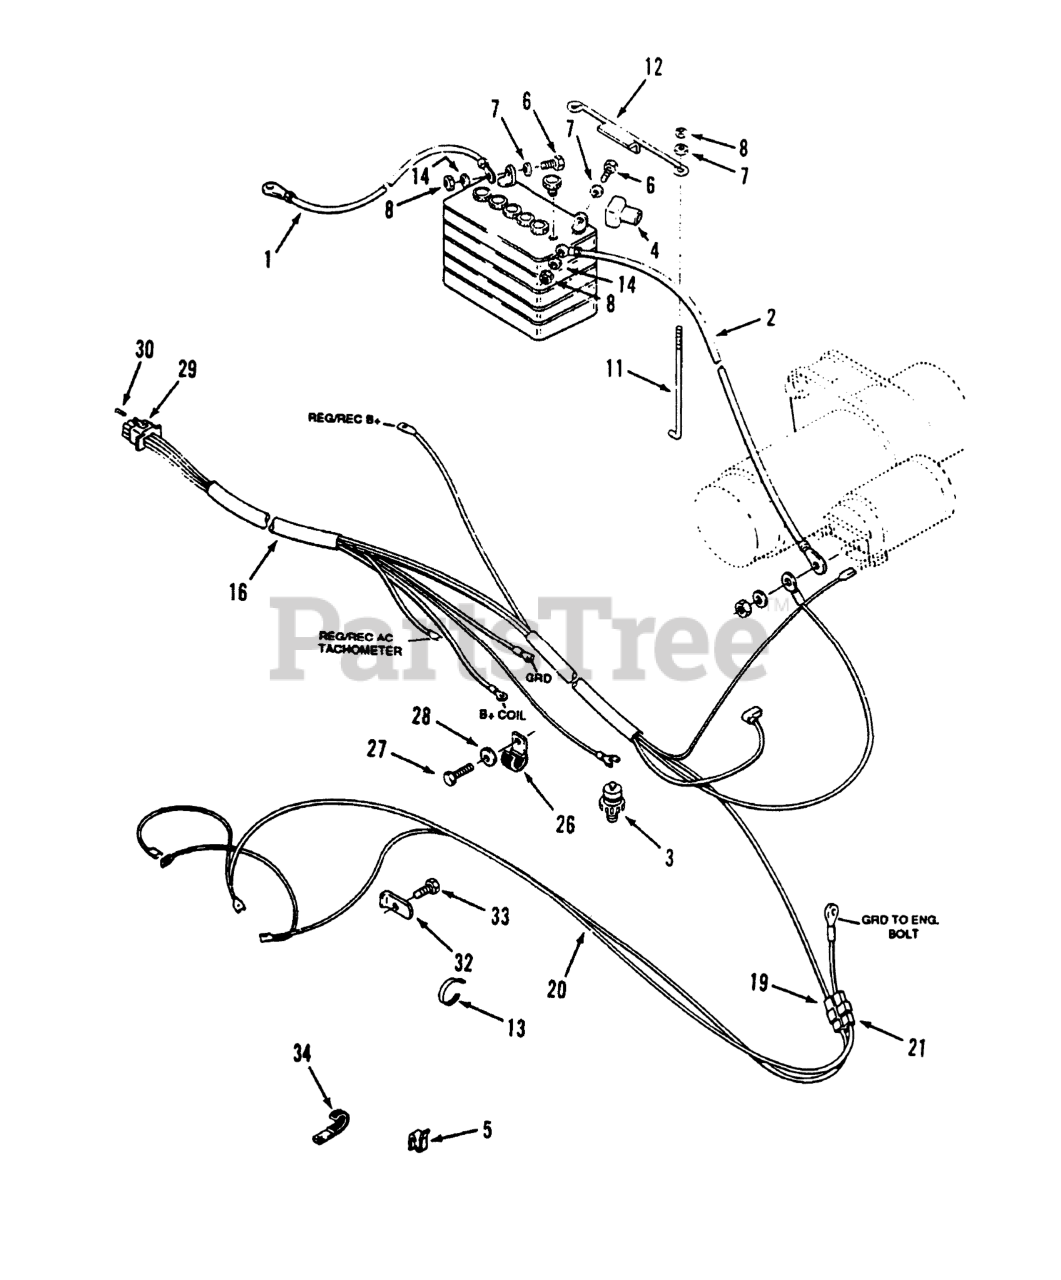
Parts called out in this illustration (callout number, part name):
1	ASS'Y-WIRE
2	SHIELD-SD DISCHARGE
3	SWITCH
4	Boot
5	SPEED CLIP
6	SCREW-HH
7	WASHER-FLAT
8	Nut
11	HOOK-BATTERY RETAIN
12	HOLDDOWN-BATTERY
13	PLASTIC TIE
16	Engine Wiring Harness
19	MALE CONNECTOR
20	HARNESS-HEADLIGHT
21	CONNECTOR BODY
26	Clip
27	Bolt
28	LOCKWASHER 1/4 IT
29	CONNECTOR CAP
30	CONTACT SOCKET
32	LOCK-HEADLIGHT
33	Bolt
34	CLIP
